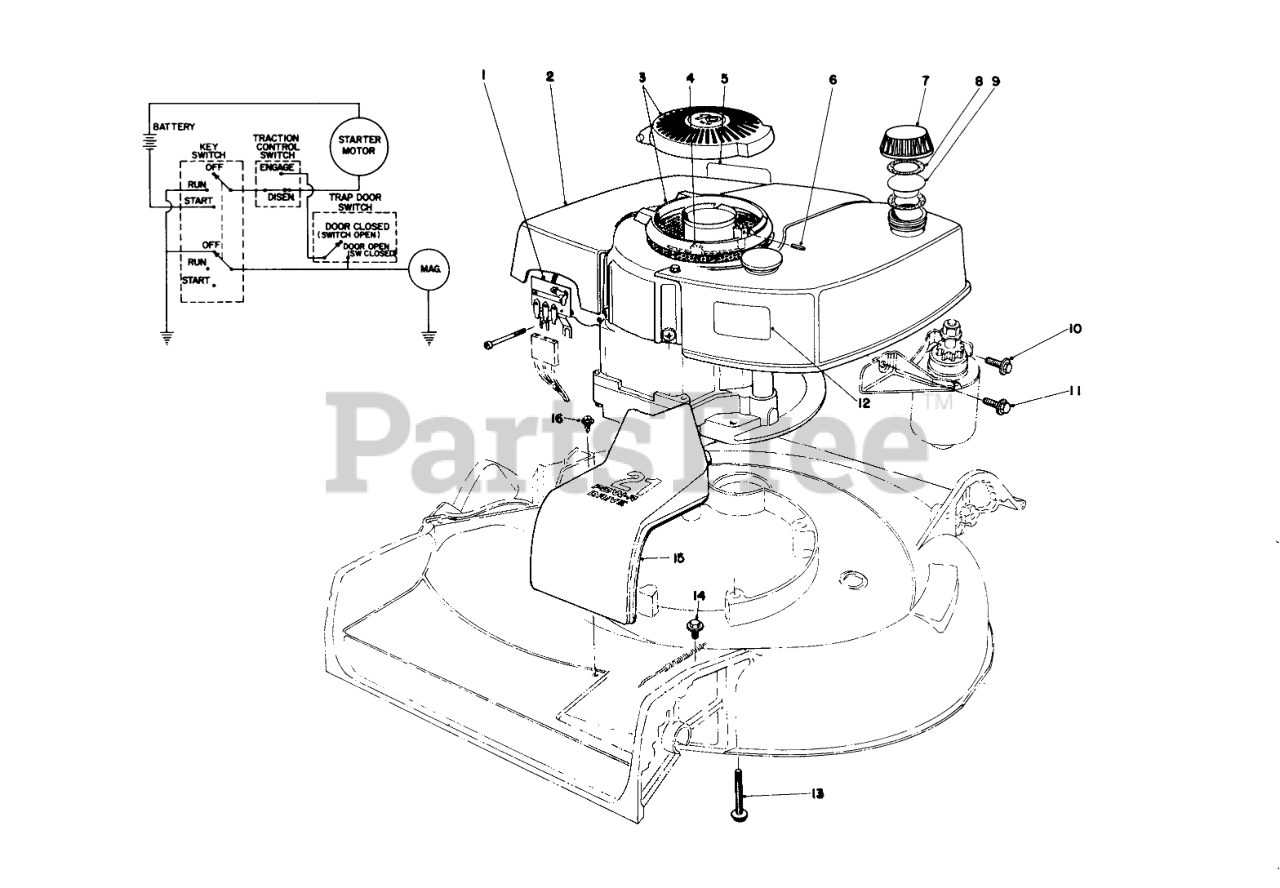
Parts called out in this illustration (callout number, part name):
1	SWITCH & TERM BLK CVR
2	Engine
3	Cover
4	WIRE CLIP
5	Decal Maintenance
6	SPRING PIN
7	Gas Cap (Incl. Ref. #8 & 9)
8	GASKET
9	GAS CAP BAFFLE
10	SCREW
11	Screw
12	Decal Engine
13	3/8-16 X 2-3/4 CAPSCR
14	SCREW-HWHTF
15	Cover Belt Drive
16	SCREW
